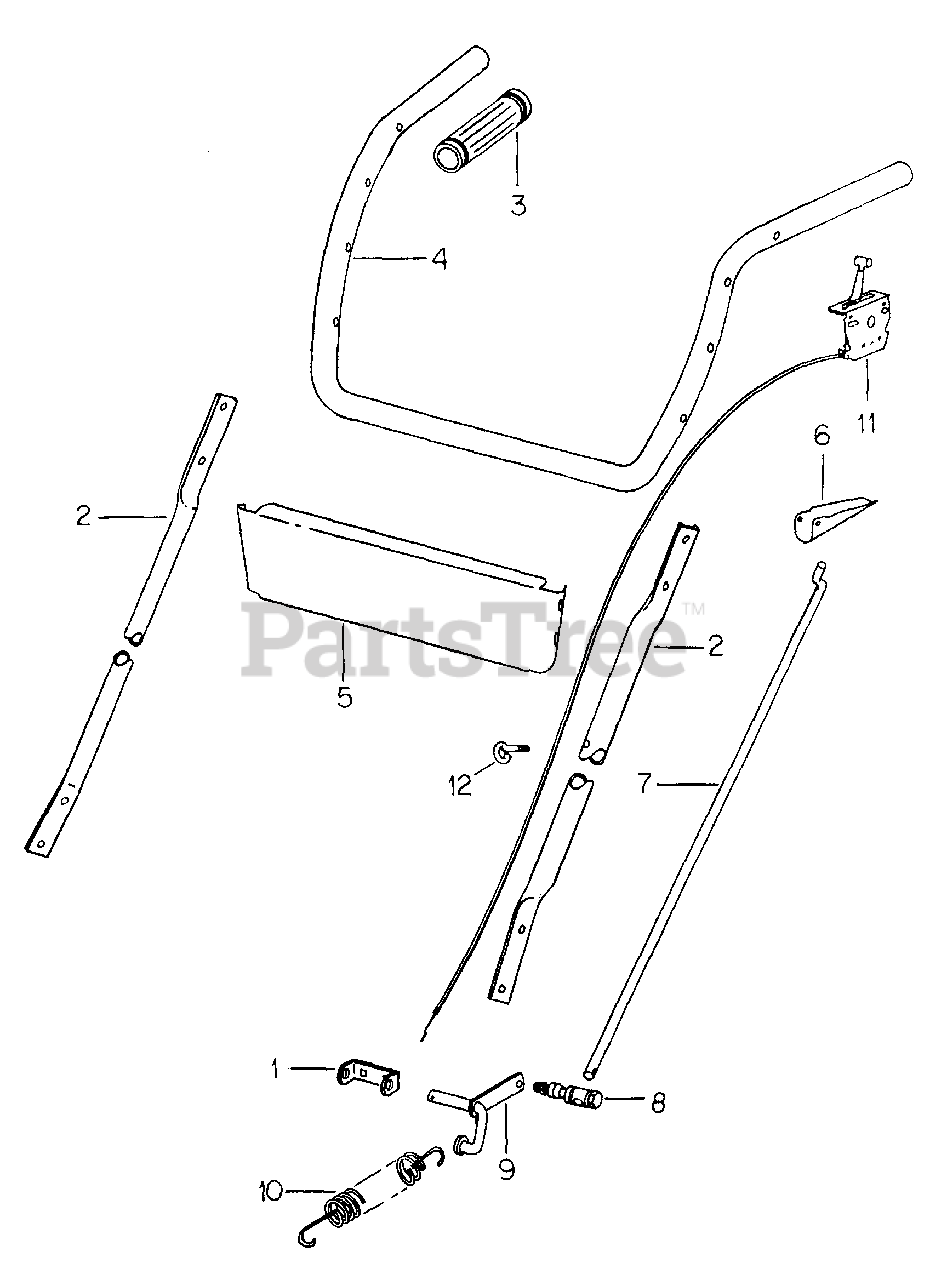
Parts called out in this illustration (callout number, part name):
1	BRACKET, PIVOT
2	EXTENSION, HANDLE BAR
3	GRIP, RUBBER HANDLE
5	PLATE, SUPPORT
6	HANDLE, CLUTCH
7	ROD, CLUTCH
7	ROD, CLUTCH ADJ
7	ROD, CLUTCH LONG
8	JOINT, BALL
9	LEVER, CLUTCH
10	SPRING, TENSION
11	CONTROL, THROTTLE
